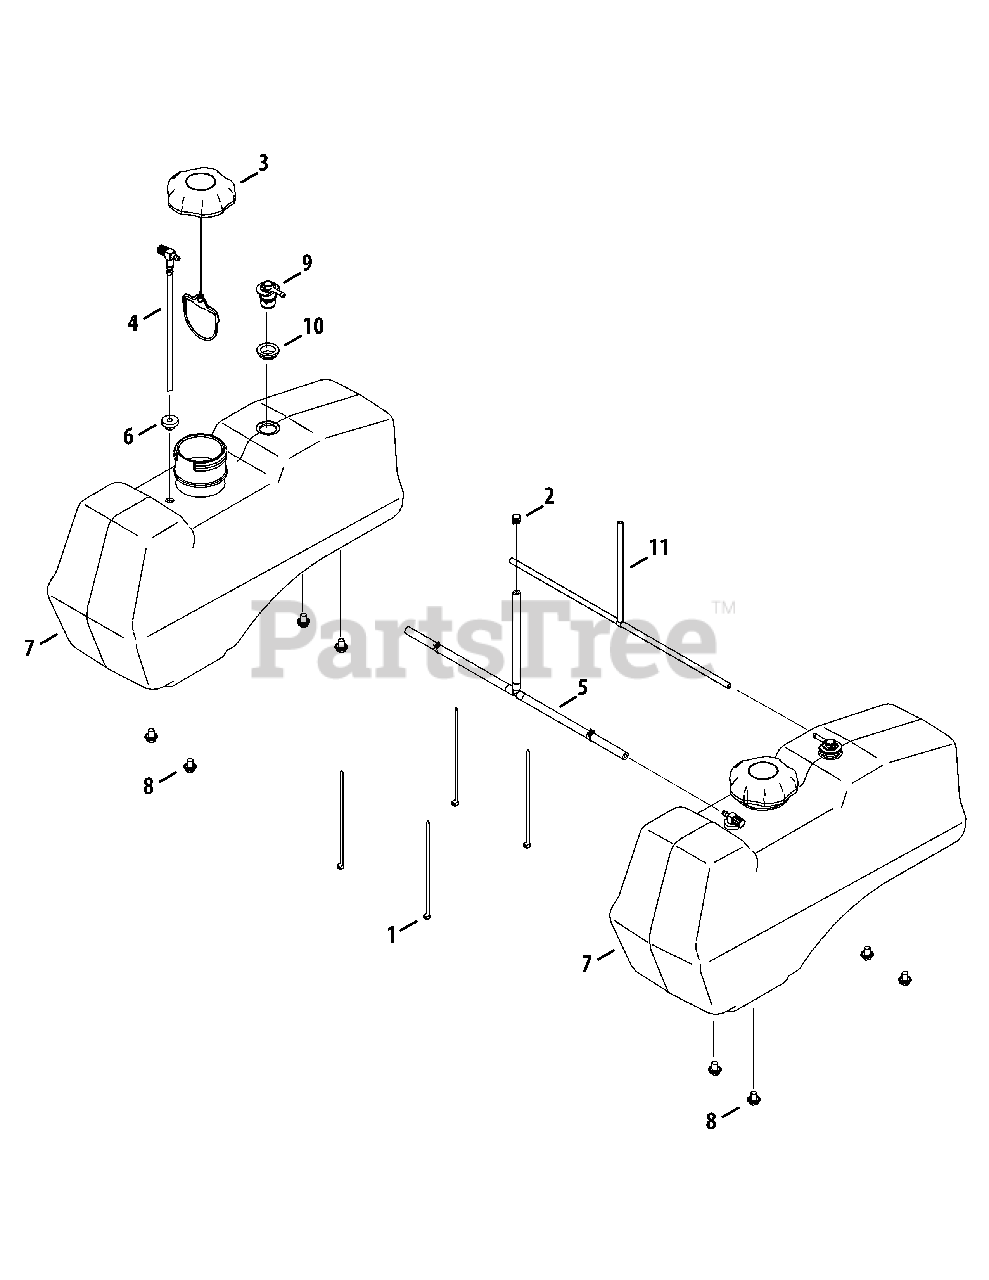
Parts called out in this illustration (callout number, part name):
1	Cable Tie
2	Hose Clamp, SAE #4: 1/4-5/8, SS
3	Fuel Cap, 3.5
4	Fuel Pickup Fitting, ON/OFF
5	Fuel Hose Assembly
5	Hose, 1/4" Fuel Line
5	Clamp, Union
5	Tee Fitting, Fuel
6	Grommet, Fuel Tank
7	Fuel Tank Assembly, 6 gal
8	Hex Cap Screw, 3/8-16 x .50 Flange
9	Fuel Rollover Valve
10	Rubber Grommet
11	Fuel Hose Assembly
11	Hose, 3/16" Fuel Line
11	Tee Fitting, Fuel
